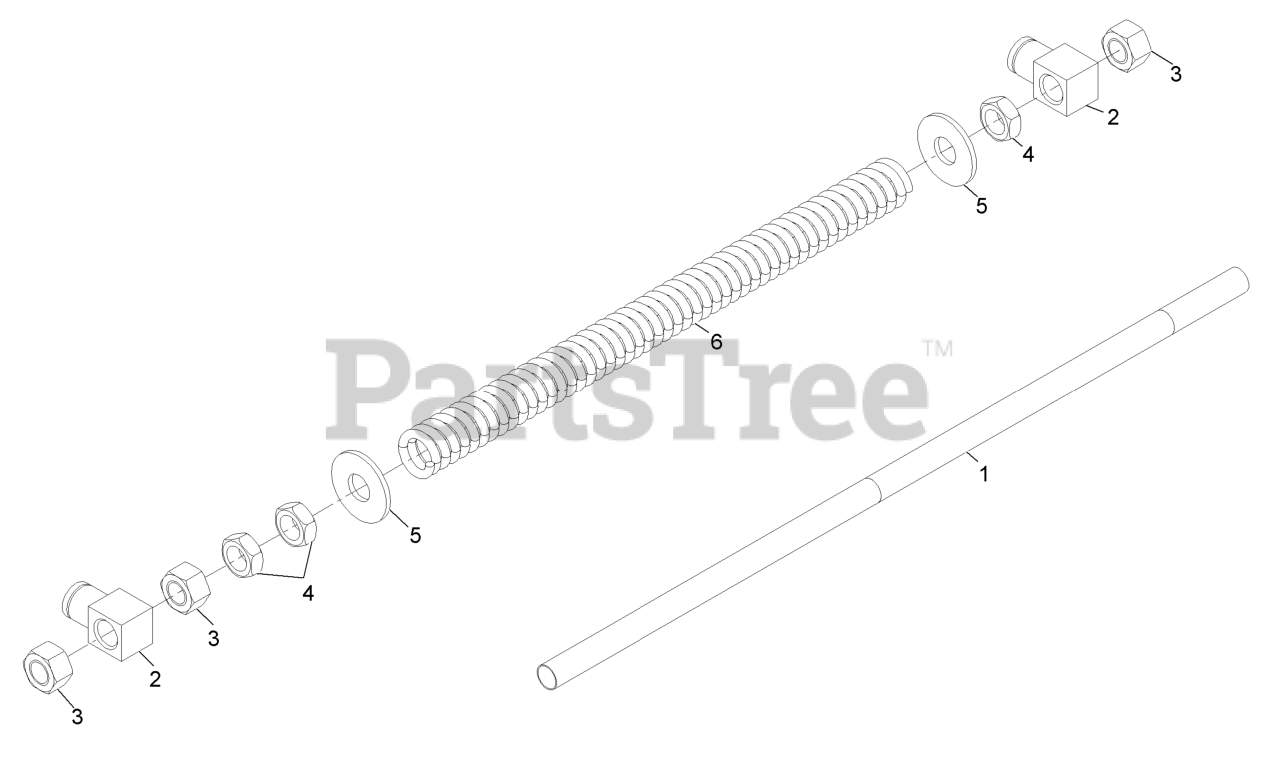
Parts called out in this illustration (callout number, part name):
1	ROD-LIFT, DECK
2	SWIVEL-DECK MOUNT, REAR
3	NUT-HEX
4	NUT-JAM
5	WASHER-FLAT
6	SPRING,DECK SUPPORT
